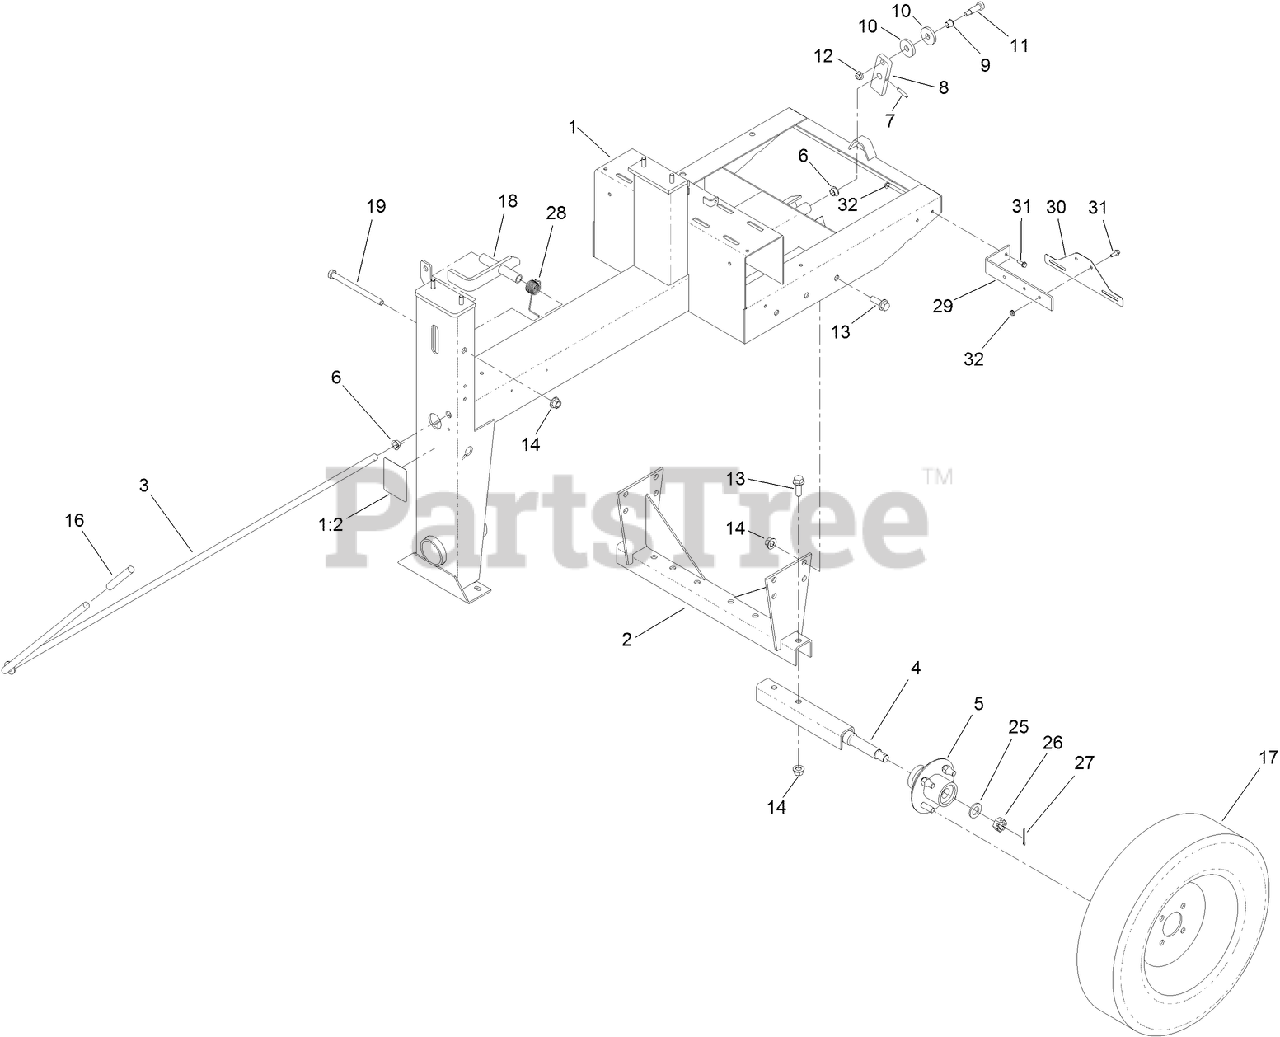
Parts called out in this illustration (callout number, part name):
1	FRAME ASM
1:2	DECAL-SAFETY CHAIN, TOWING
2	SUPPORT-AXLE
3	LEVER-CLUTCH
4	AXLE-HALF
5	HUB ASM
6	BUSHING-FLANGE
7	PIN-SPRING
8	LINK-CLUTCH
9	BUSHING-FLANGE
10	WASHER-FLAT
11	SCREW-HSBH
12	NUT-HF, NI
13	SCREW-HHF
14	NUT-LOCK
16	GRIP-HANDLE
17	TIRE AND RIM ASM
18	LATCH-DRUM
19	SCREW-HH
25	WASHER-FLAT
27	PIN-COTTER
28	SPRING-TORSION
29	BRACKET-UNIVERSAL
30	HOLDER-PLATE, LICENSE
31	SCREW-HHF
32	NUT-KEPS
